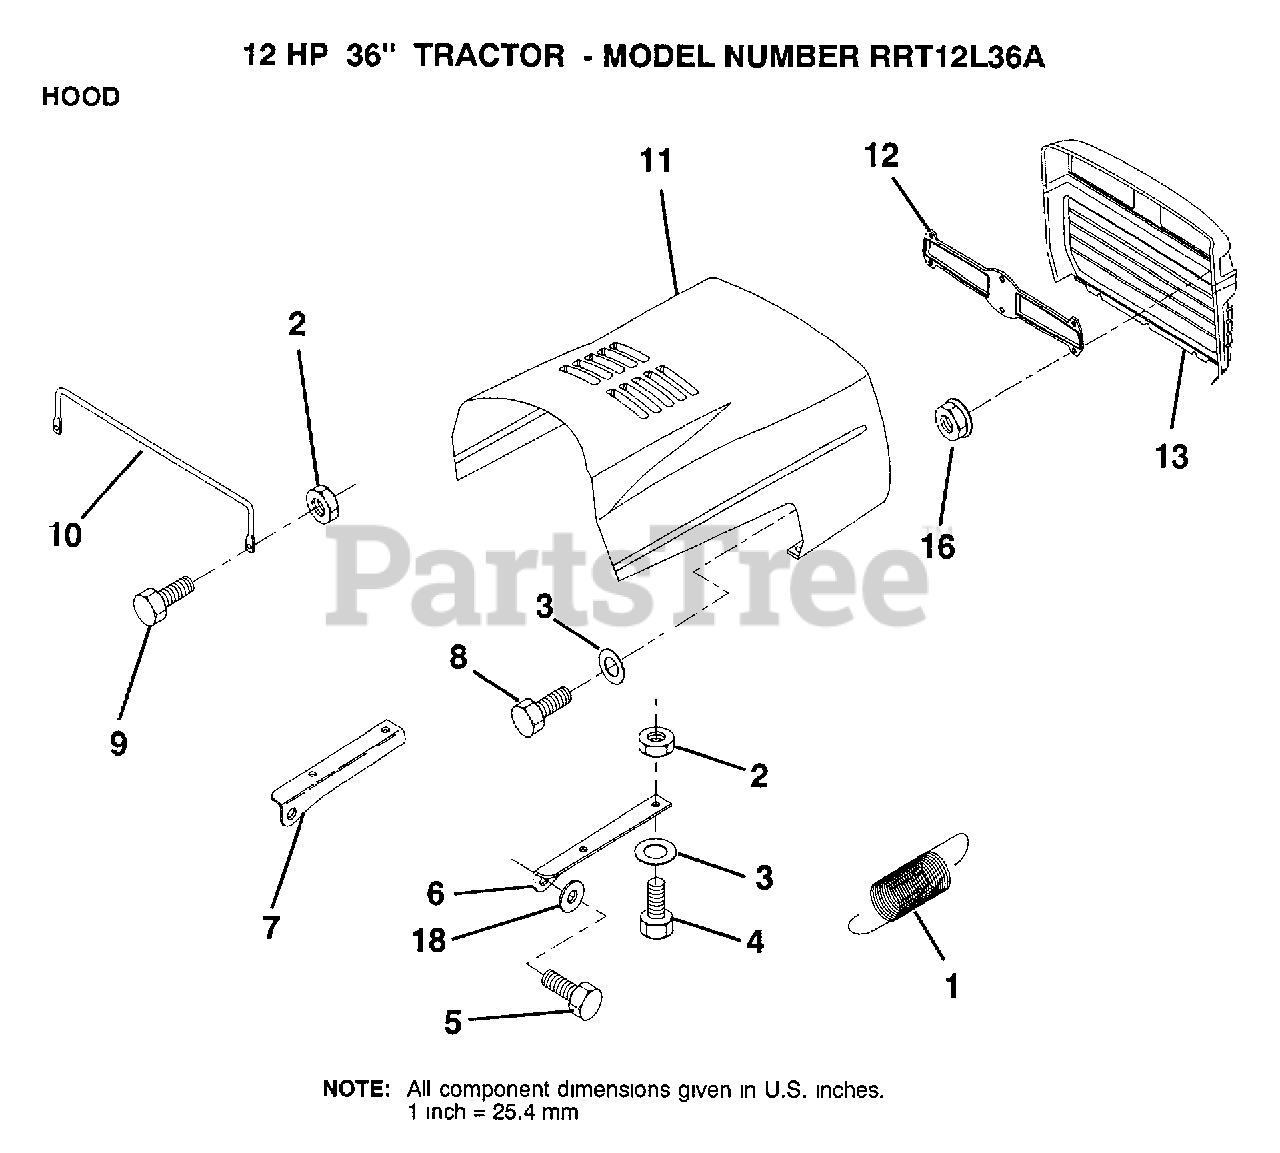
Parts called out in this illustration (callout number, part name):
1	EXT SPRING
2	NUT
3	WASHER
4	BOLT
6	BRKT HOOD RH
7	BRKT HOOD LH
10	"BRACE,HOOD"
11	HOOD
13	GRILL (BLACK)
16	NUT
18	WASHER
